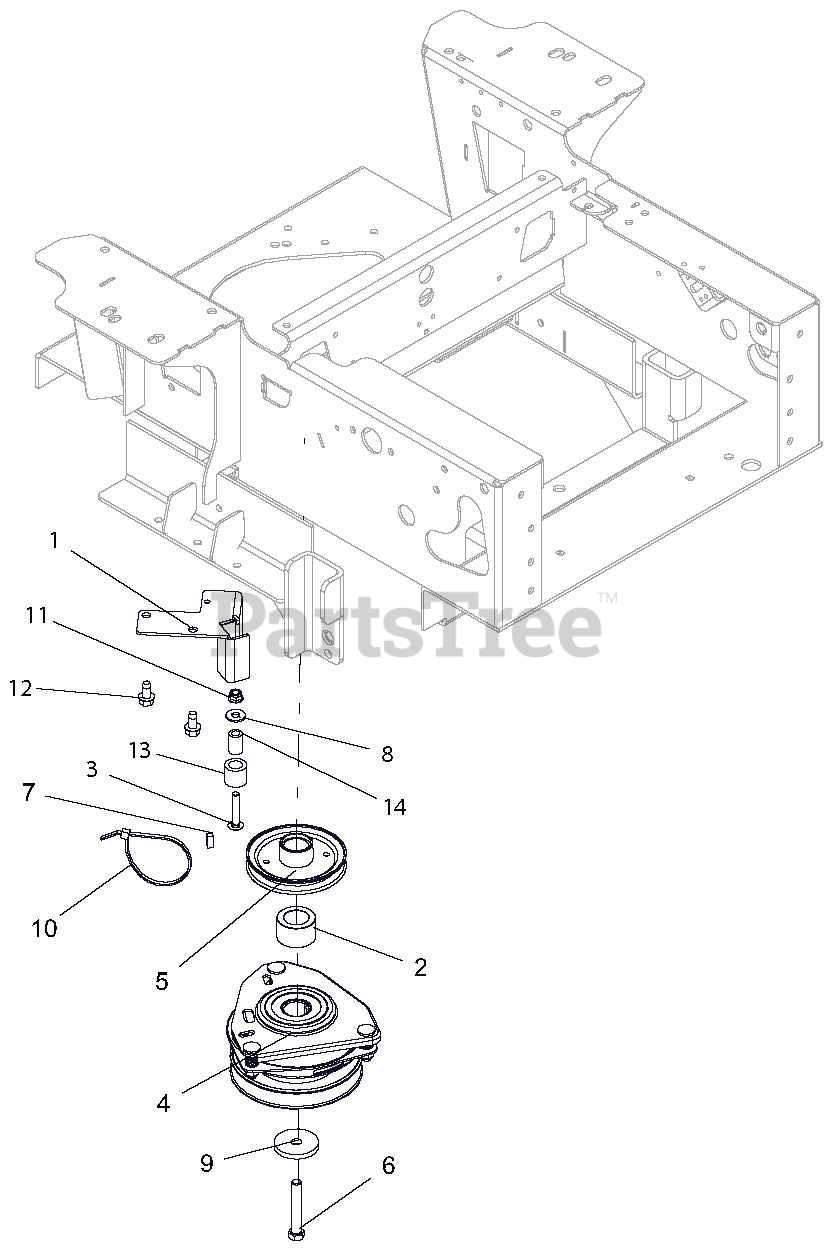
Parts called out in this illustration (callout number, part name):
1	BRKT, CLUTCH STOP
2	SPCR, 1.125 C 1.750 X 1.060
3	BLT-RDHDSQSHNK .31-18X1.75 YWZC
4	CLUTCH, OGURA GT1A-EH01
5	PULLEY, 4.50 OD X 1.127 ENGINE-BLACK
6	BLT-HEX .44-20X2.75 GR5 EP80 YWZC
7	KEY-SQ .250X.250X.625
8	WSHR-FL-STL.38X.875X.083 YWZC
9	WSHR-FL-STL .469X2.00X.25 YWZC
10	CABLE, TIE 5.50 LG
11	NUT-LK-NYL-FLG .31-18 YWZC
12	SCR-TAP .38-16X.75 HWH TR YWZ
13	BUMPER, RUBBER .62 X 1.0 X .88 LG
14	BUSH.,S.391X.622X.95 ST REV A
